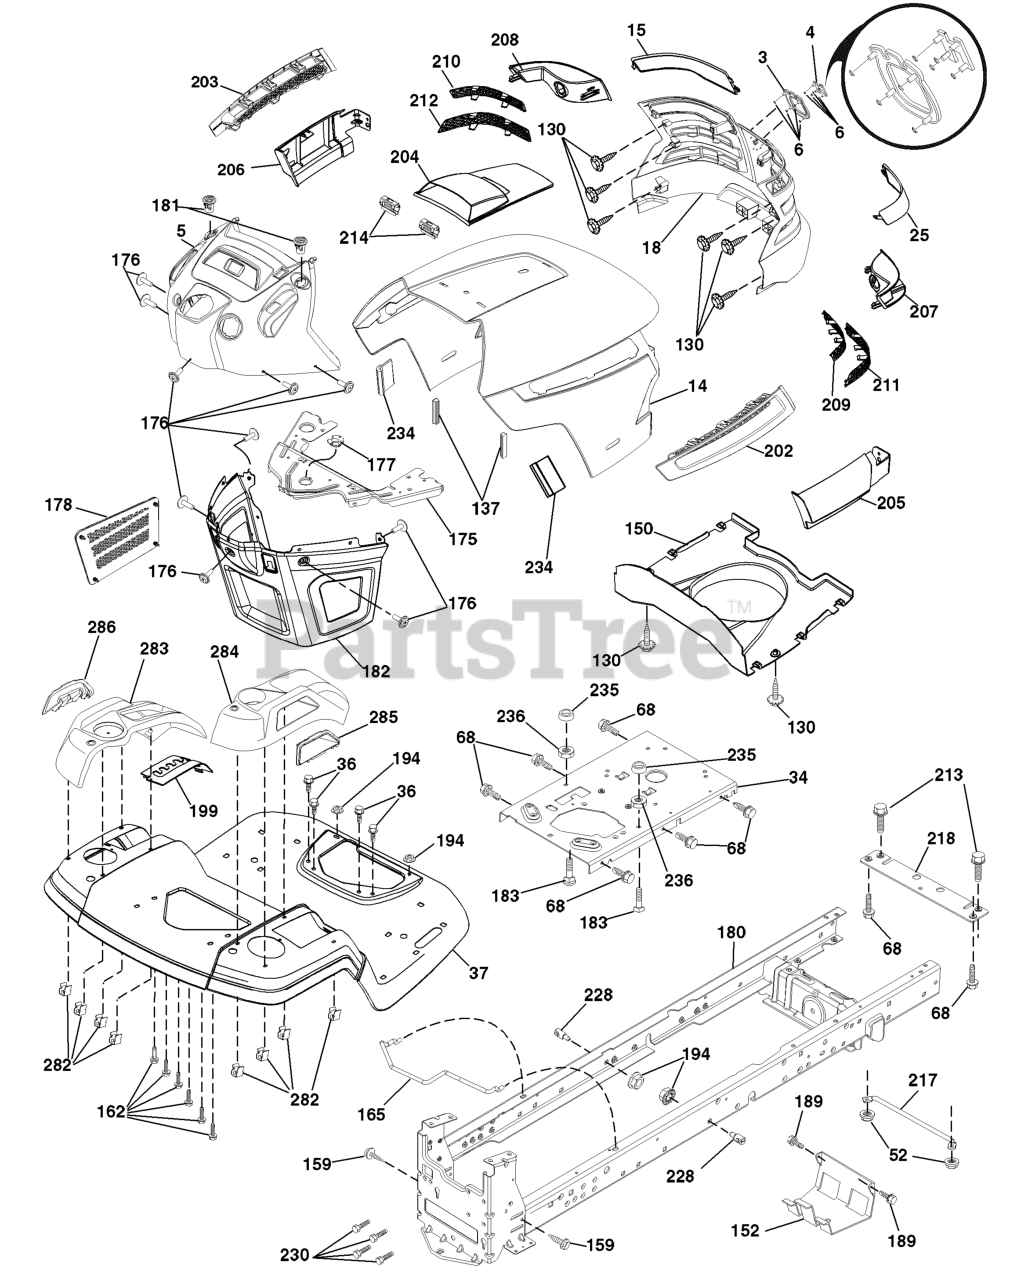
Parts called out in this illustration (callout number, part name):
3	TRIM.HUSQ.TG/CRD.SERVICE
4	RP LOGO
5	DASH.ASM.HUSQ.GT.E.RECT.W/CK
6	NUT PUSH M
14	HOOD
15	LENS.LH.TEX.GT.HUSQ.CL
18	GRILL.ASM.HUSQ.TG/CRD.W/TRIM
25	LENS.RH.TEX.GT.HUSQ.CL
34	PLATE.ENGINE.WELDED.CHASSIS
36	SCREW 5/16"
37	RP FENDER.TLT.FS.W/CPH.422
52	LOCKNUT
68	Screw Thdrol 5/16-18 x 1/2
130	SCREW.#10 X 0.750.BOS
137	BUMPER DASH
150	AIR.DUCT.HOOD.TEX.GT.HUSQ
152	SHIELD.BROWNING.W/TEX
157	SCREW, 3/8-16X3/4
175	PLATE.CROSSMEMBER.HUSQ
176	SCREW.#10-24X5/8.RN.QU
177	BUSHING, STEERING
178	CARGO.ASM.NET.TXGT.W/C
180	CHASSIS
181	BUSHING.MNT.FEND.CRGO.
182	DASH.LOWER.COMMON.12V.ADAPTOR
183	BOLT.5/16-18X1-1/4 FULL.THREAD
189	SCREW
194	NUT LOCK HEX FLANGE 5/16-18
199	PLATE.DECK.LIFT.HUSQ.LT
202	VENT.SIDE.HOOD.HUSQ.RH.GREY
203	VENT.SIDE.HOOD.HUSQ.LH.GRAY
204	HOOD VENT
205	SKIRT.HOOD.SIDE.HUSQ.RH.GREY
206	SKIRT.HOOD.SIDE.HUSQ.LH.GREY
207	BEZEL.RH.TEX.GT.HUSQ
208	BEZEL.LH.TEX.GT.HUSQ
209	INSERT.HEX.GRILL.HUSQ.GREY
210	INSERT.HEX.GRILL.HUSQ.
211	INSERT.HEX.GRILL.HUSQ.
212	INSERT.HEX.GRILL.HUSQ.
213	BOLT
214	CLIP.RETAINER.TINNER.
217	ROD.PIVOT.HOOD
218	X-PIECE.HOOD.STOP.NON/
228	STUD.FASTNER.W/ANTI-ROTATE
230	SHOULDER BOLT 5/16-18TT
234	BUMPER.HOOD.TEX.HUSQVARNA
235	SPACER FENDER
236	NUT.CENTERLOCK.5/16-
282	CLIP.RETAINER.CONSOLE.LT.HUSQ
283	CONSOLE.DECK.LIFT.HUSQ.N/FR.GR
284	Console Shift
285	CONSOLE INSERT RH
286	CONSOLE.INSRT.LH.HUSQ.LT.BLACK
287	SCREW 1/4X20
